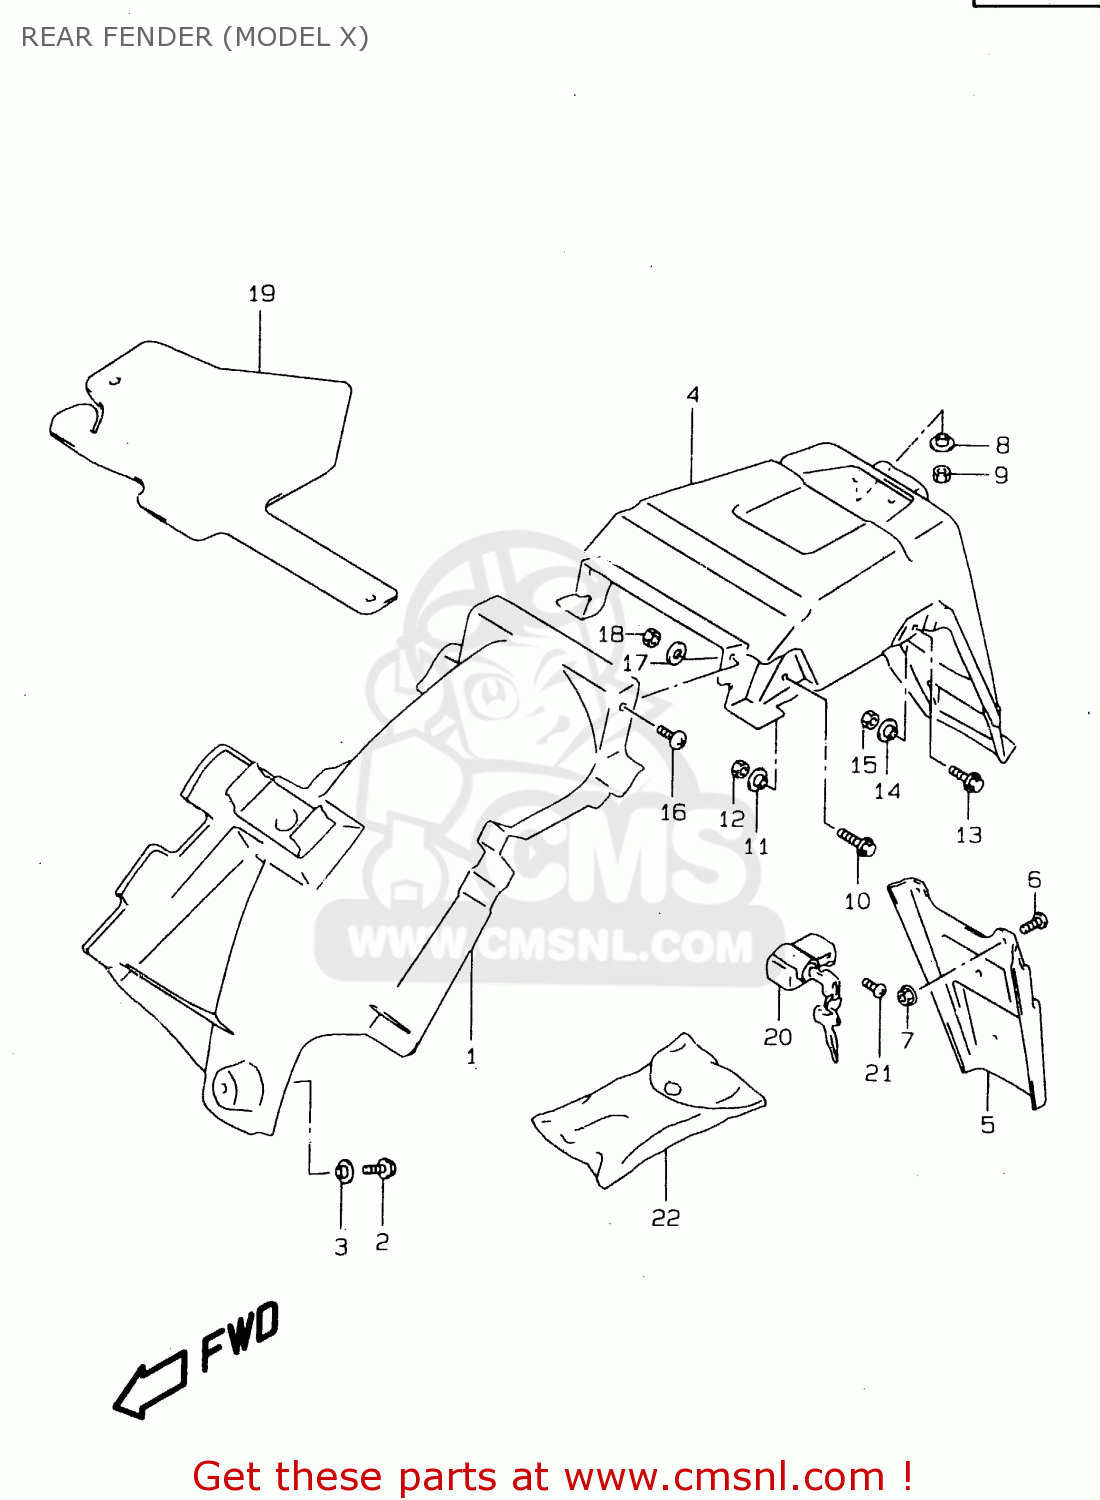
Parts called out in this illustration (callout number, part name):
1	BODY COMP,REAR FENDER
2	BOLT
3	WASHER
4	BODY,RR FENDER RR
5	EXTENSION,RR FENDER
6	SCREW
7	NUT
8	WASHER
9	NUT
10	BOLT
11	WASHER
12	NUT
13	BOLT
14	WASHER
15	NUT
16	SCREW
17	WASHER(6.5X18X1.6)
18	NUT
19	MUDFLAP,RR FENDER FR
20	LOCK SET,HELMET
21	SCREW(6X14)
22	TOOL ASSY
